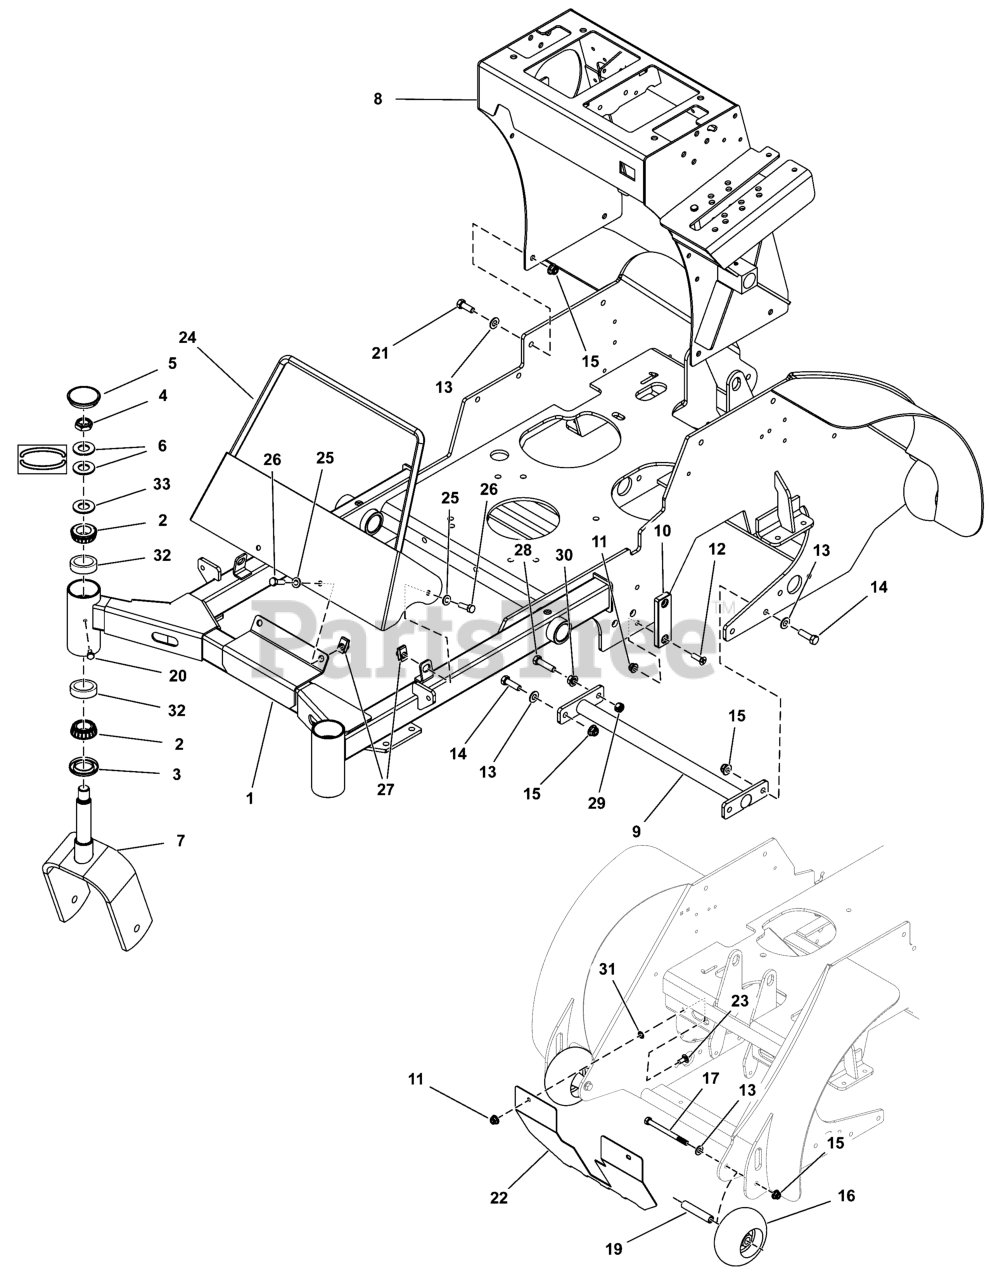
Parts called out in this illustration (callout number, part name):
1	FRAME
2	BEARING, TAPERED ROLLER, 1"
3	SEAL, GREASE
4	NUT, 3/4-16, HEX JAM NYLON LOCK
5	CAP, GREASE, LOW PROFILE
6	WASHER, BELLEVILLE - 1.500 X .755
7	WELD, CASTER YOKE - RED
8	WELD, CONTROL TOWER, SRSZ1
9	WELD, CENTER CROSS BRACE, SRSZ1 - BLK
10	PAD, FRICTION, .375 X 1.25 X 4.00
11	NUT, 5/16-18 HEX NYLOCK FLANGE NUT
12	SCREW, 5/16-18 X 1, PHILLIPS HD, BZ
13	WASHER, 3/8 SAE
14	BOLT, 3/8-16 X 1-1/4" GD5 CZ
15	NUT, 3/8 - 16 HEX NYLOCK FLANGE
16	WHEEL, ANTI SCALP, 5"
17	BOLT, 3/8-16 X 4-1/2" GD5 CZ
19	SPACER, .38 X .63 X 3.38, CZ
20	BOLT, 1/4-28 X 1/2, GD5 YZ
21	BOLT, 3/8-16 X 1" GD5 CZ
22	PLATE, HEAT SHIELD, SRSZ1
23	BOLT, 5/16-18 X 3/4, CARRIAGE, GD5, CZ
24	WELD, FRONT FRAME GUARD, SRSZ1
25	WASHER, 5/16" SAE
26	BOLT, 5/16-18 X 3/4 GD5
27	BODY CLIP, 5/16-18-7GA MATERIAL
28	BOLT, 3/8-16 X 1-1/2" GD5 CZ
29	NUT, Hex, Side Lock, 3/8-16
30	NUT, 3/8-16 Hex Large Serrated Flange
31	5/16" PUSH-ON NUT RETAINER, STL, CZ
32	CUP, BEARING (SV)
33	WASHER, 3/4 SAE
